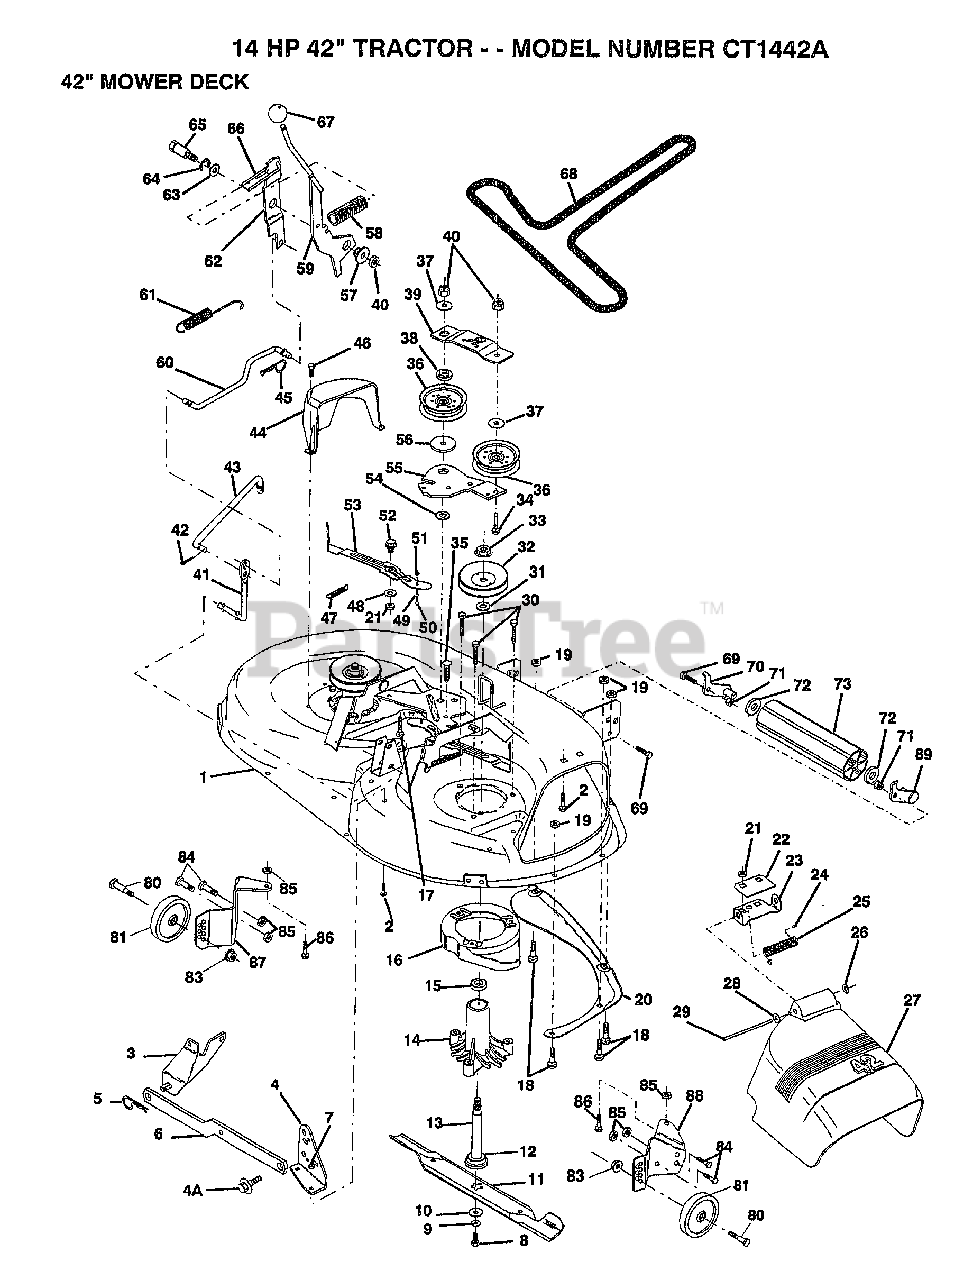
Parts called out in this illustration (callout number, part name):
2	BOLT
3	BRKT ASM SWAY BAR
4	BRKT DECK SW BAR
4A	BOLT SHD 5/16-18
7	NUT
8	BLADE BOLT
10	WASHER BLADE
11	"BLADE.42"" HIPERF"
12	BEARING.BALL
14	HSG ASM MANDREL
15	BEARING
17	BOLT CARRIAGE
18	BOLT
19	NUT
22	STIFFENER BRKT
23	DEFLECTOR BRKT
24	CAP-SLEEVE LT
25	SPRING TORSION
26	NUT PUSH M
27	DEFLECTOR.SHIELD
28	WASHER
29	HINGE ROD
31	WASHER
34	BOLT
35	XMAS TREE FASTNER
36	FLAT IDLER PULLEY
37	WASHER GT
38	RETAINER SPACER
39	IDLER ARM STIFF
41	PIVOT ROD
43	CLUTCH ROD SECOND
45	RETAINER M
46	SCREW.1/4-20X5/8
47	SPRING EXTENSION
48	HARD SMALL WASHER
50	SHOULDER BOLT
51	LOCKNUT
53	BRAKE PAD ARM ASM
54	HARDENED WASHER
55	IDLER ARM
56	SPACER RETAINER
57	BUSHING
59	CLUTCH ARM PRI AS
60	"ROD, CLUTCH PRIM"
61	RETURN SPRING
62	CLUTCH ARM SECOND
63	WASHER
64	RING
65	SHOULDER BOLT
66	SPRING KEEPER
68	BELT-V.92.4.MWR
69	BOLT
72	WASHER
80	BOLT M
81	WHEEL.GAGE.BLK.PL
83	NUT
84	BOLT
